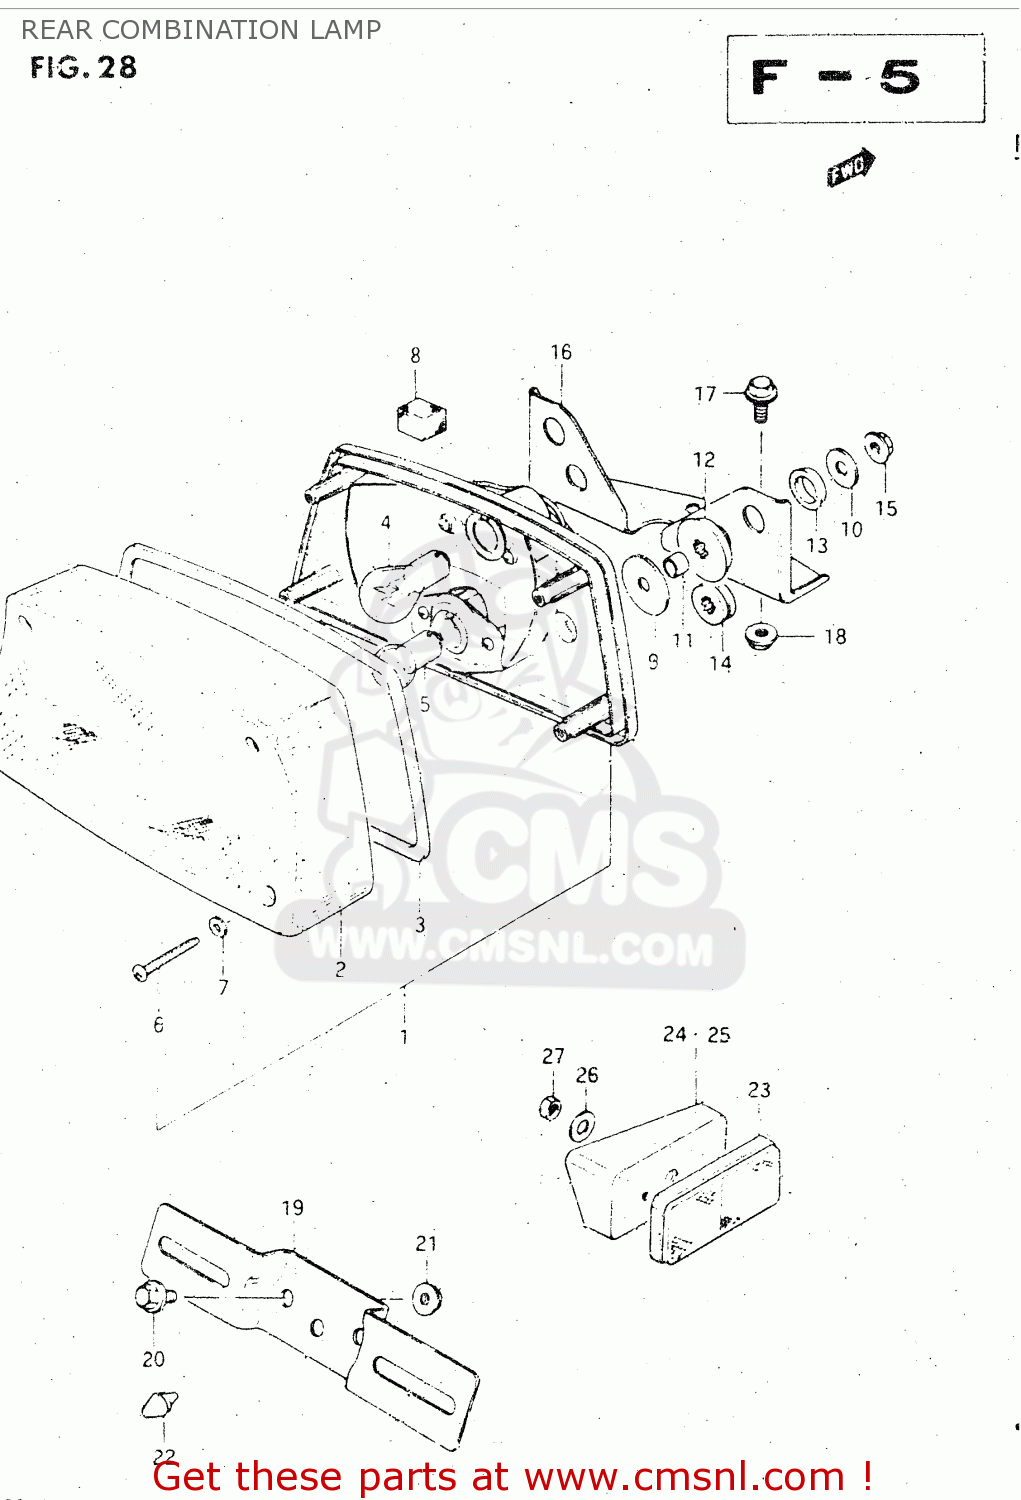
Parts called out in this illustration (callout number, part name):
1	LAMP ASSY, REAR COMBINATION
2	LENS
3	GASKET
4	BULB(12V21/5W)
5	BULB
6	SCREW ,4X25
7	GASKET (NAS)
8	CUSHION,REAR COMBINATION LAMP
9	WASHER
10	WASHER(6,5X22X1.6)
11	SPACER
12	CUSHION
13	CUSHION
14	CUSHION,RR COMBINATION
15	NUT
16	BRACKET,REAR COMBINATION LAMP
17	BOLT
18	NUT
19	PLATE,RR LICENSE
20	BOLT 6X12
21	NUT
22	CUSHION
23	REFLECTOR,REFLEX
24	SPACER, RH
25	SPACER, LH
26	WASHER(5.2X16X1)
27	NUT
